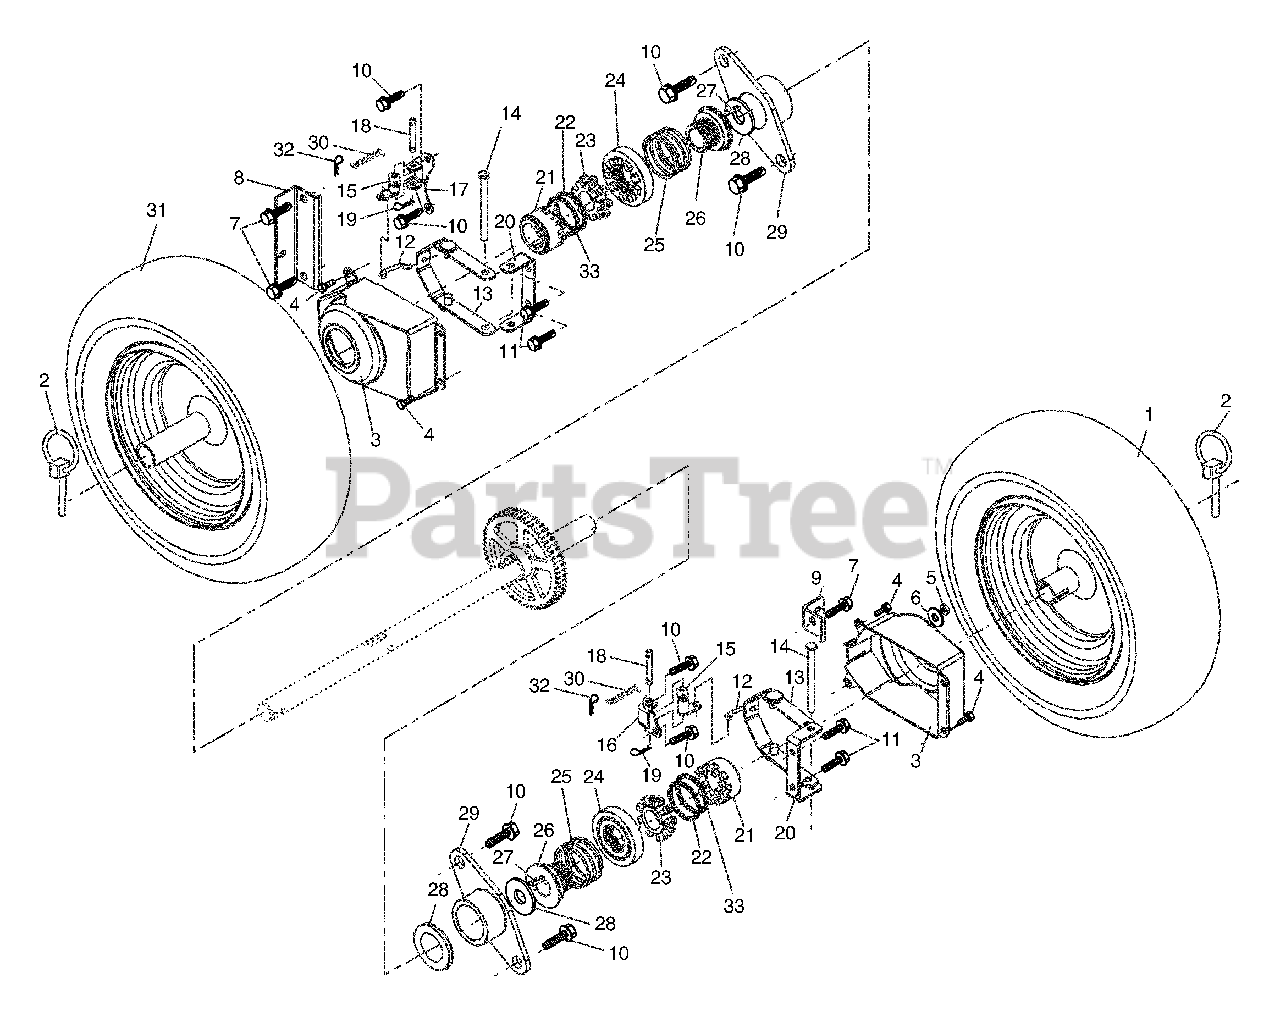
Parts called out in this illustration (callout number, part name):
1	Wheel Assembly, 16", Power Steering, LH
2	Pin, Klik 1/4
3	Cover, Power Steering
4	Bolt, Shoulder #10-24 x 5/8
5	Nut, Lock 5/16-18
6	Washer, Flat 5/16
7	Screw, Hex Head 3/8-16 x 1
8	Bracket, Steering Cable, RH
9	Bracket, Steering Cable, LH
10	Screw, Hex Head 5/16-18 x 5/8
11	Screw, Hex Head 5/16-18 x 1/2
12	Link, Steering Lever
13	Yoke, Steering
14	Pin, Steering Lever
15	Bellcrank Assembly
16	Bracket Assembly, LH Steering
17	Bracket Assembly, RH Steering
18	Pin, Steering Bellcrank
19	Retainer, Hairpin
20	Bracket, Lever Assembly
21	Driver, Wheel
22	Ring, Wire Retainer
23	Lobe, Wheel
24	Slide, Clutch
25	Spring, Clutch Slide
26	Lobe, Axle
27	Key, Square 1/4
28	Washer, Thrust (1")
29	Bearing, Axle
30	Spring, Return
31	Wheel Assembly, 16", Power Steering, RH
32	Clip, Retainer
33	Ring, Retaining
